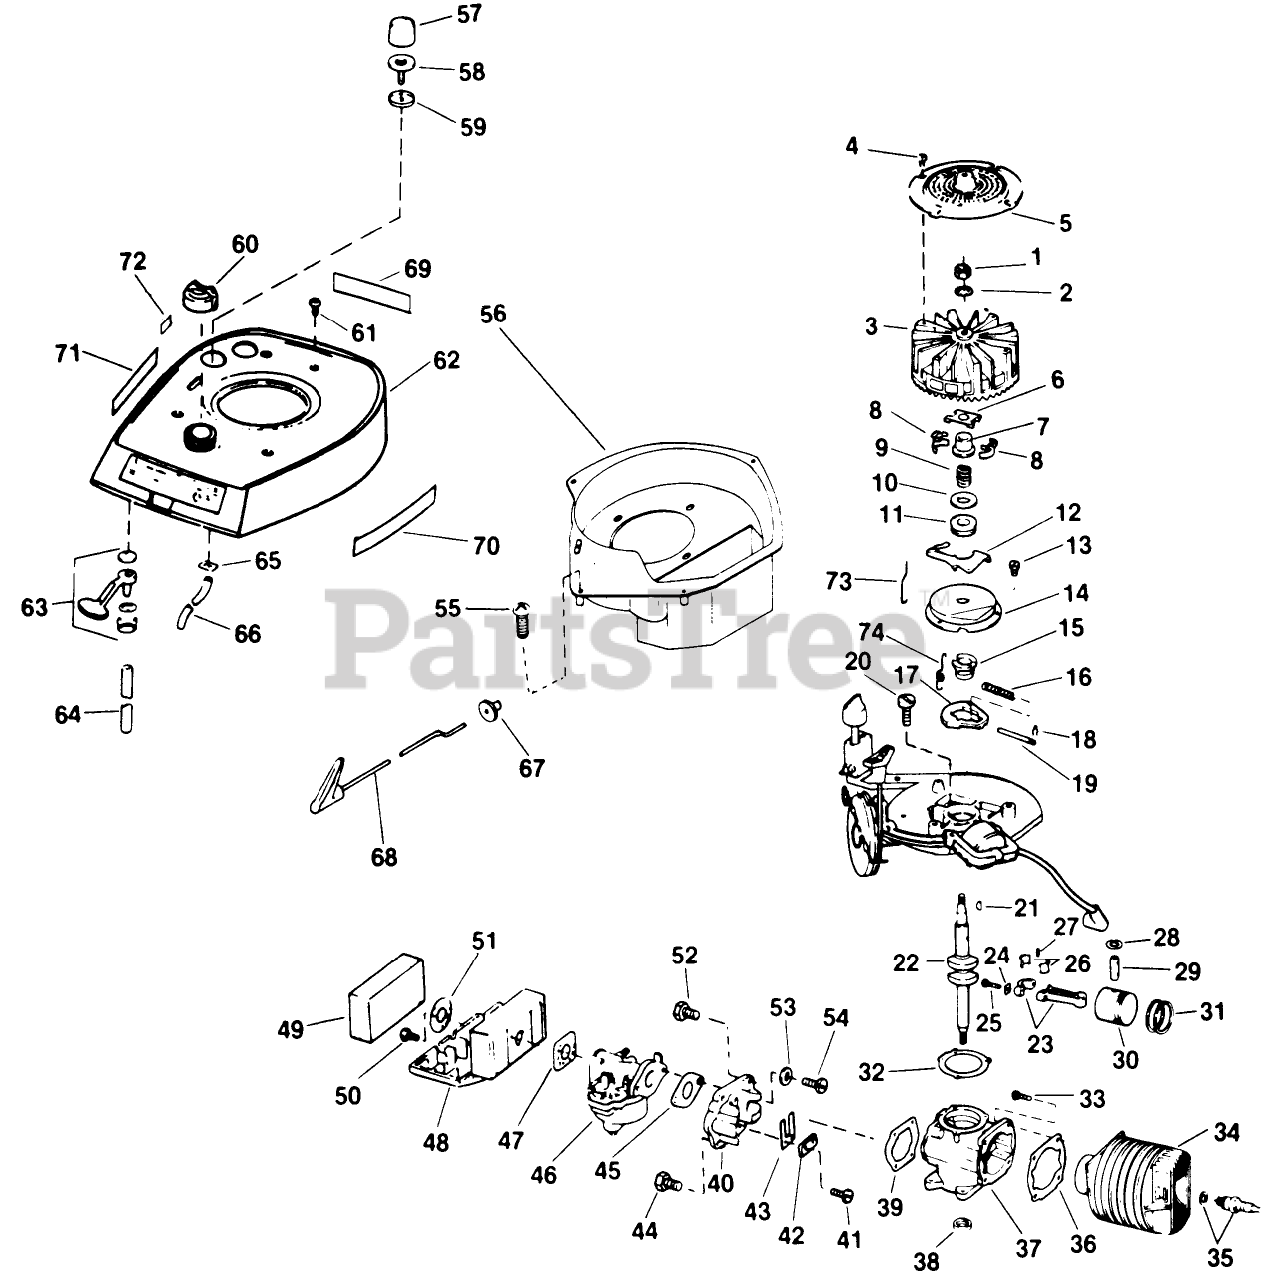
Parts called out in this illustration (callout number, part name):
4	SCREW F
5	FLYWHEEL SCREEN
7	COLLAR S
9	SPRING S
11	THRUST COLLAR S
12	LEVER-GOVERNOR S
13	SCREW S
14	DUST COVER S
15	SPARK ADV. S
16	SPARK ADV. SPRING S
17	FLYWEIGHT S
18	SPARK ADJ. SPRING
19	PIN,SPARK ADV. S
26	LINER ASM
28	RING-RETAINING
32	GASKET S
35	Spark Plug and Gasket
36	GASKET S
39	GASKET S
40	REED PLATE AY. S
42	PLATE-BACKUP, REED
44	SCREW S
45	GASKET S
47	GASKET S
49	AIR FILTER S
50	SCREW S
51	WASHER S
52	SCREW S
59	CUP-BULB
61	SCREW S
65	LOCKNUT S
67	GROMMET
68	KNOB & ROD AY. S
75	SPRING BAR
